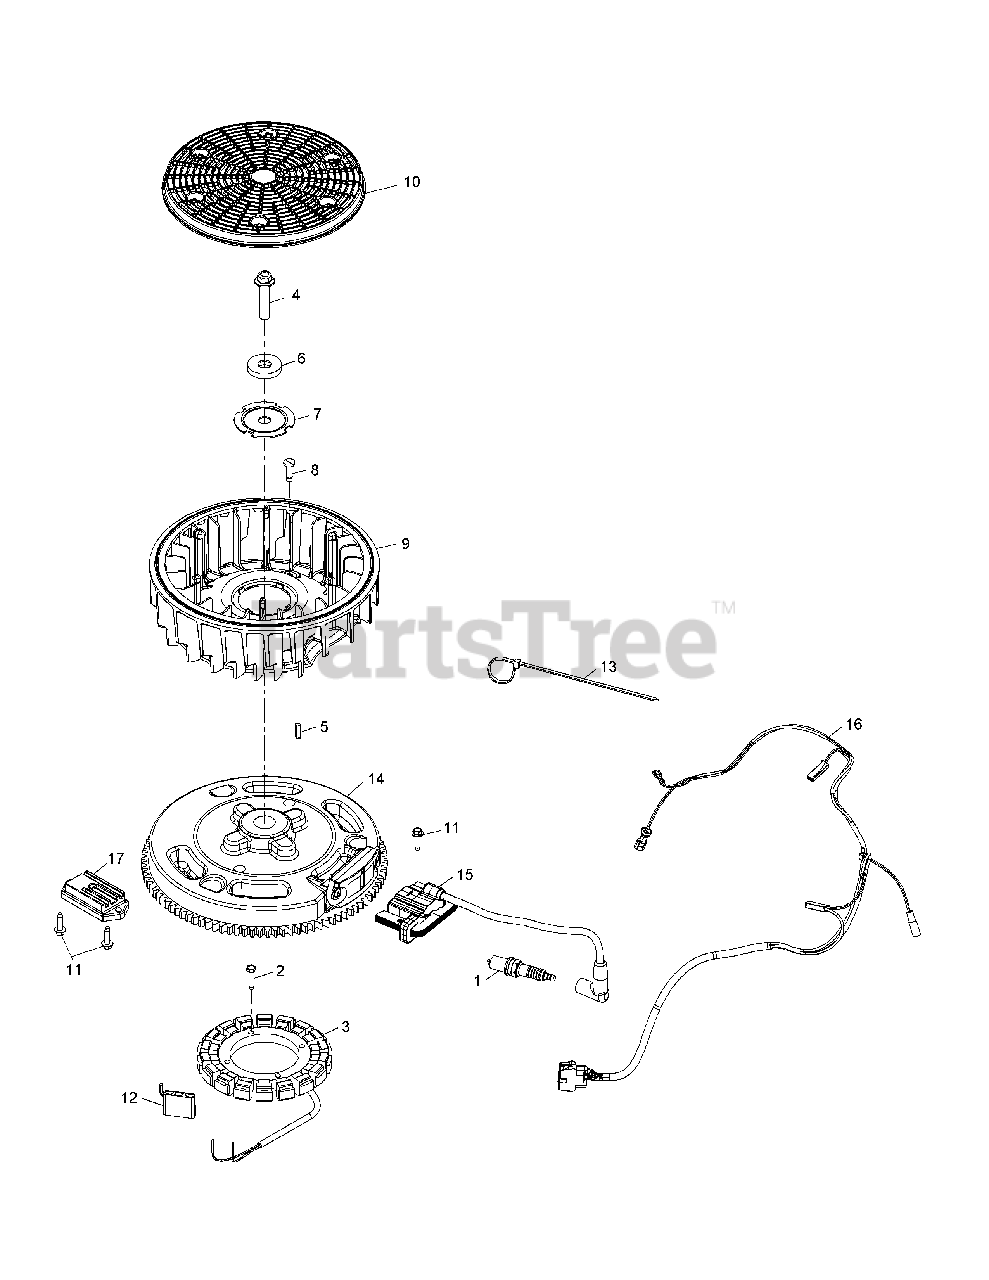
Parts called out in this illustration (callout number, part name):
2	Thread Forming Screw
3	15 Amp Stator Kit
4	Hex Flange Screw
7	Fan Mounting Plate
8	Flywheel Fan Retainer
11	Thread Forming Screw
14	Flywheel Assembly
15	Ignition Module
16	Wiring Harness
17	Rectifier Regulator
